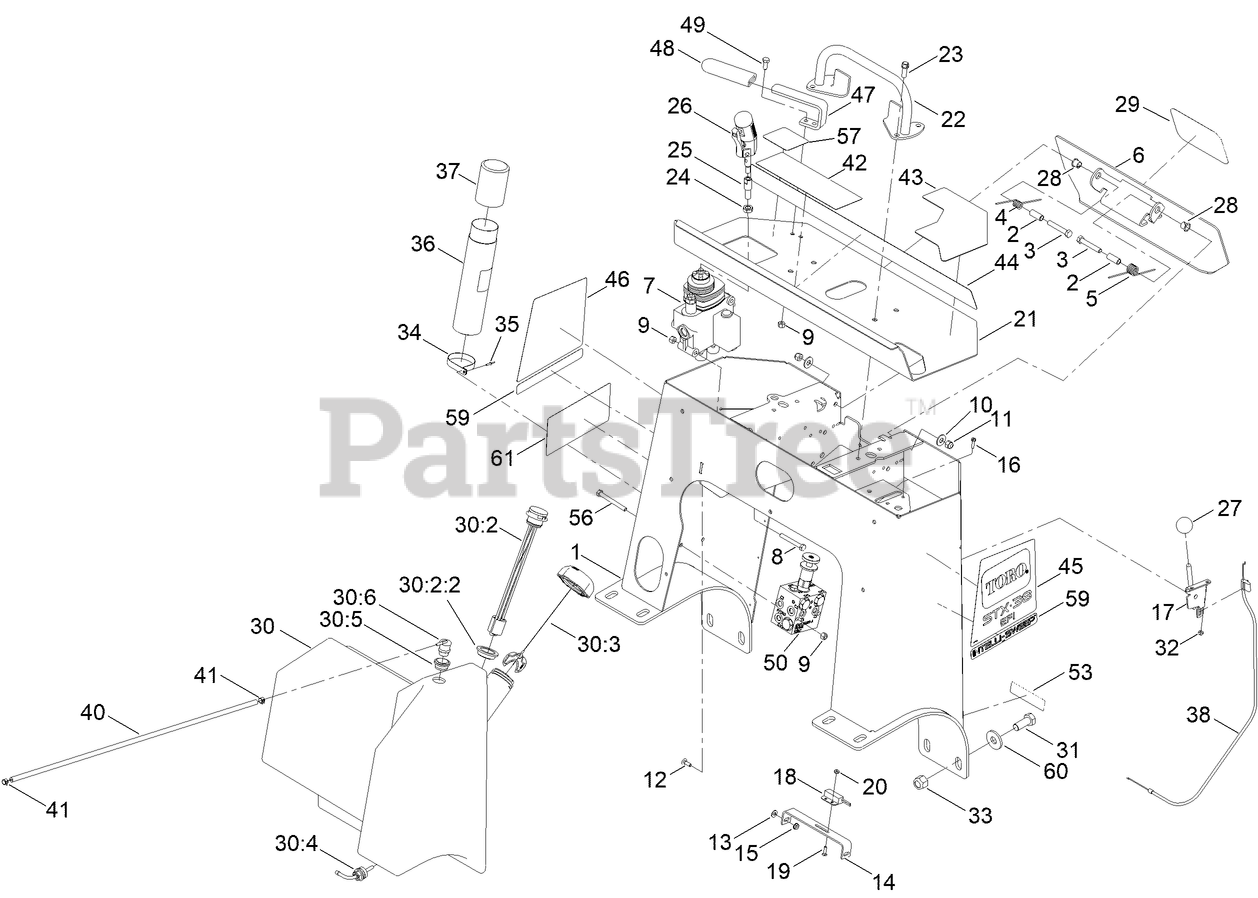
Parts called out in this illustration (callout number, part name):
2	SPACER-SPRING
3	SCREW-HH
4	SPRING-TORSION, LH
5	SPRING-TORSION, RH
6	BACKUP PLATE ASM, [BLK-TXT]
7	HYD VALVE ASM
8	SCREW-HH
9	NUT-LOCK, NI
10	WASHER-FLAT
11	NUT-LOCK, NI
12	BOLT-CARR
13	WASHER-FLAT
14	PLATE-SWITCH
15	NUT-KEPS
16	SCREW-HWH
17	LEVER-CONTROL
18	SWITCH-PROXIMITY
19	SCREW-CARR
20	NUT-KEPS
21	PANEL-CONTROL
22	BAR-REFERENCE
23	SCREW-TAPTITE
25	ADAPTER-HANDLE
26	TWO BUTTON HANDLE GRIP ASM
28	BUSHING-NYLINER
30	FUEL TANK ASM
30:2	GAUGE ASM
30:4	FITTING-FUEL, BULKHEAD
30:5	GROMMET
30:6	VALVE-VENT, FUEL
31	SCREW-HH
32	NUT-LOCK, NI
33	NUT-LOCK, NI
34	CLAMP-R
35	RIVET-POP
36	TUBE-MANUAL
37	CAP-HOUSING
38	CABLE-CONTROL
40	HOSE-FUEL
41	CLAMP-HOSE
42	DECAL-WARNING
43	DECAL-CONSOLE, LH
44	DECAL-CONSOLE, RH
45	DECAL-LOGO,LH
46	DECAL-LOGO,RH
47	BAR-ARM REST
48	GRIP-LEVER
49	SCREW-HH
50	SWEEP MANIFOLD ASM
53	DECAL-ARRESTOR, SPARK
56	SCREW-HH
57	DECAL-JOYSTICK
59	DECAL-INTELLISWEEP
60	WASHER-HARDENED
61	DECAL - SERVICE
